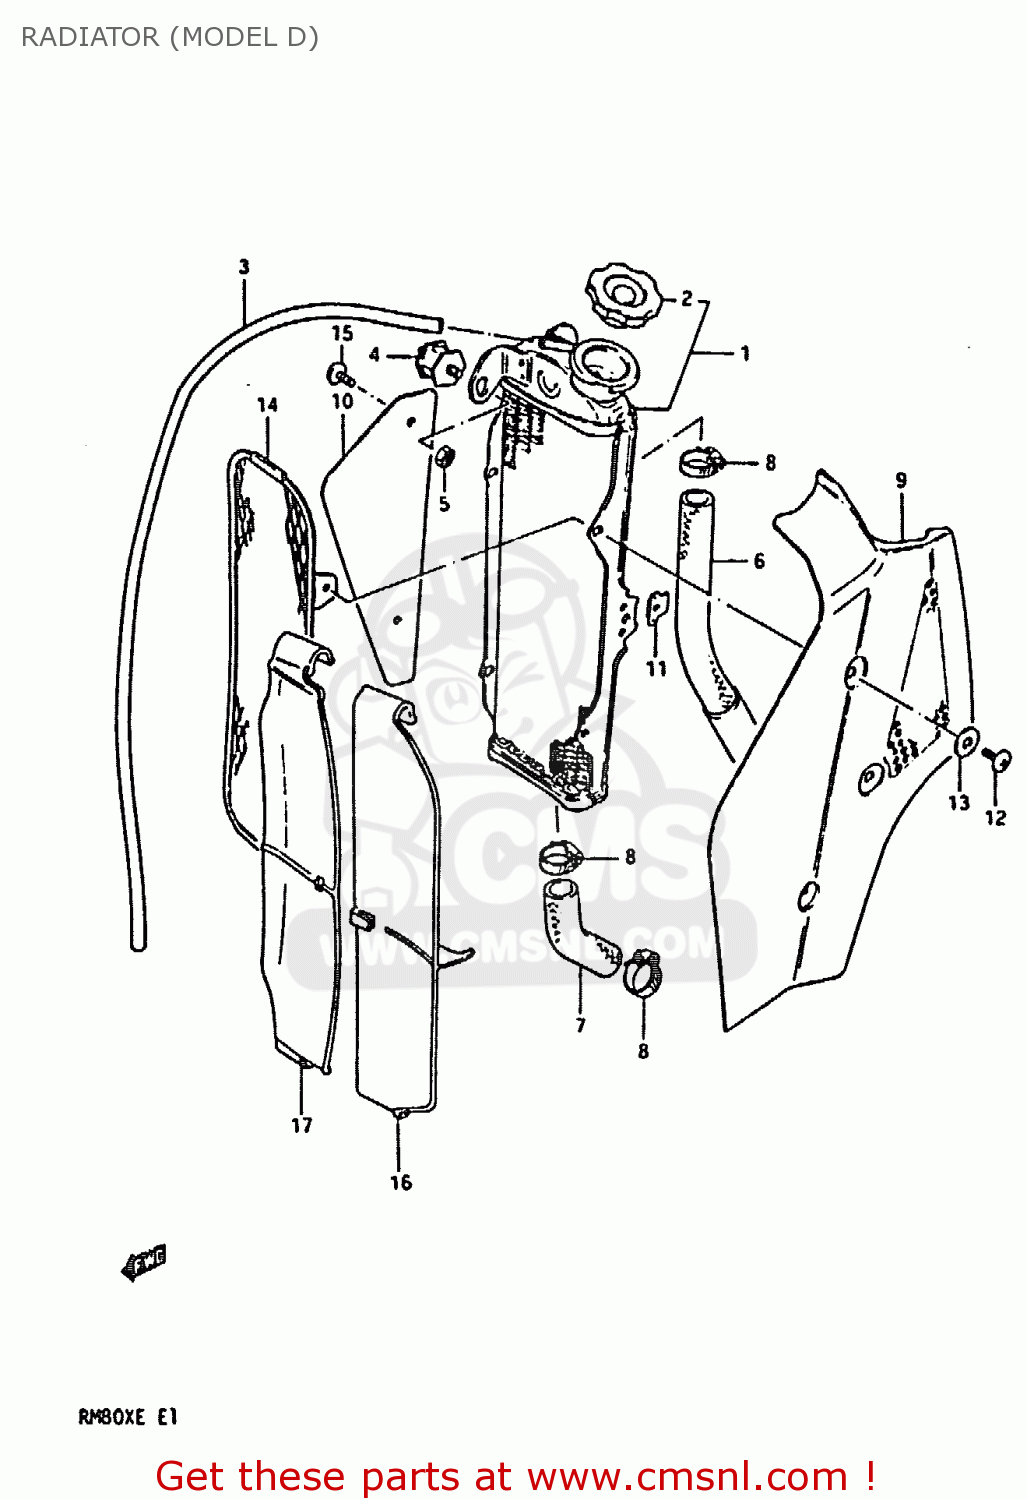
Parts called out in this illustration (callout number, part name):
1	RADIATOR ASSEMBLY,WATER
2	CAP,RADIATOR
3	HOSE,BREATHER
4	CUSHION,RADIATOR
5	NUT
6	HOSE,RADIATOR INLET
7	HOSE,RADIATOR OUTLET
8	CLAMP
9	COVER,RADIATOR,OUTER
10	COVER, INSIDE
11	PLATE,RADIATOR COVER F
12	SCREW M5X12 DIN 7985/N
13	WASHER(5.2X16X1)
14	BUMPER,RADIATOR
15	SCREW M5X12 DIN 7985/N
16	LOUVER,RADIATOR
17	LOUVER,RADIATOR
